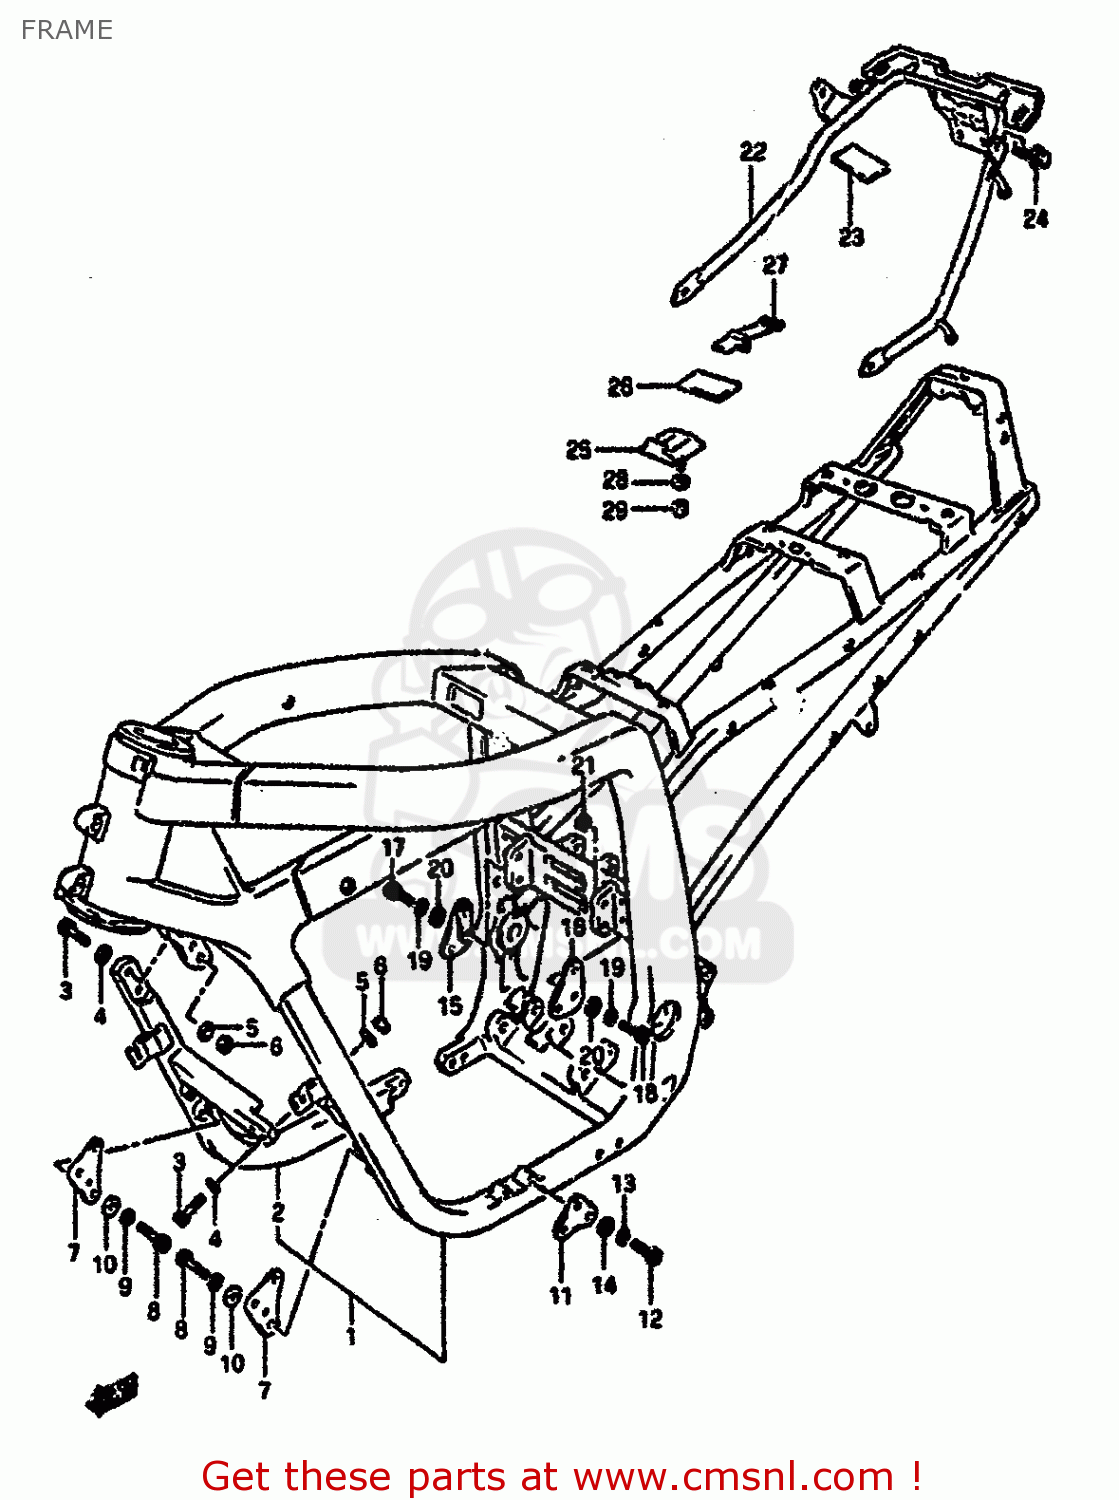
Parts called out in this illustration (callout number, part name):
1	FRAME
2	TUBE COMP,FRAME DOWN,RIGHT
3	BOLT, LH
4	WASHER (10.1X21X2.3)
5	WASHER
6	NUT
7	PLATE,ENG MTG NO.1
8	BOLT, FRONT LH
9	WASHER,LOCK
10	WASHER (8.2X20X1.6)
11	PLATE,ENGINE MOUNT NO.2
12	BOLT, FRONT LH
13	WASHER,LOCK
14	WASHER (8.2X20X1.6)
15	PLATE,ENGINE MOUNT NO.3,R
16	PLATE,ENGINE MOUNTING NO
17	BOLT, FRONT RH
18	BOLT(8X22)
19	WASHER,LOCK
20	WASHER (8.2X20X1.6)
21	NUT
22	GRIP, REAR
23	TAPE,FRAME PROTECTOR
24	BOLT
25	HOLDER,TOOL
26	CUSHION
27	BAND
28	WASHER
29	NUT
